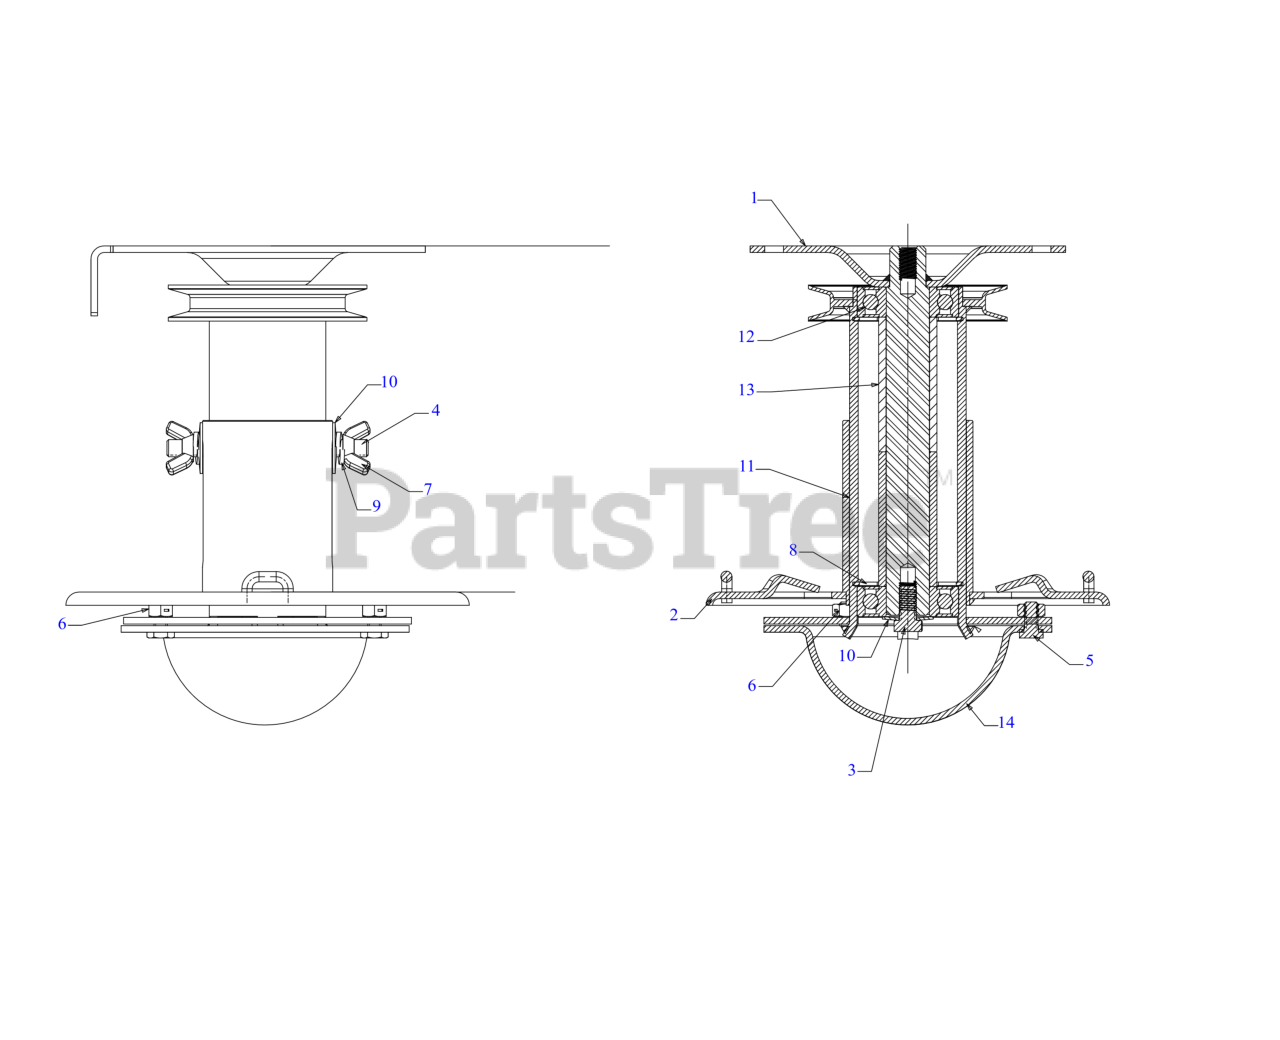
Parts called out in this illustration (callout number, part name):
1	NOT SERVICEABLE
2	NOT SERVICEABLE
3	HEX SCREW 5/16-24 x .62
4	NOT SERVICEABLE
5	SCREW 1/4-20X.5 GR5
6	HEX LOCK NUT
7	NOT SERVICEABLE
8	RETAINING RING
9	LOCK WASHER 5/16
10	BELL WASHER
11	NOT SERVICEABLE
12	BALL BEARING
13	NOT SERVICEABLE
14	SKID ASSEMBLY
